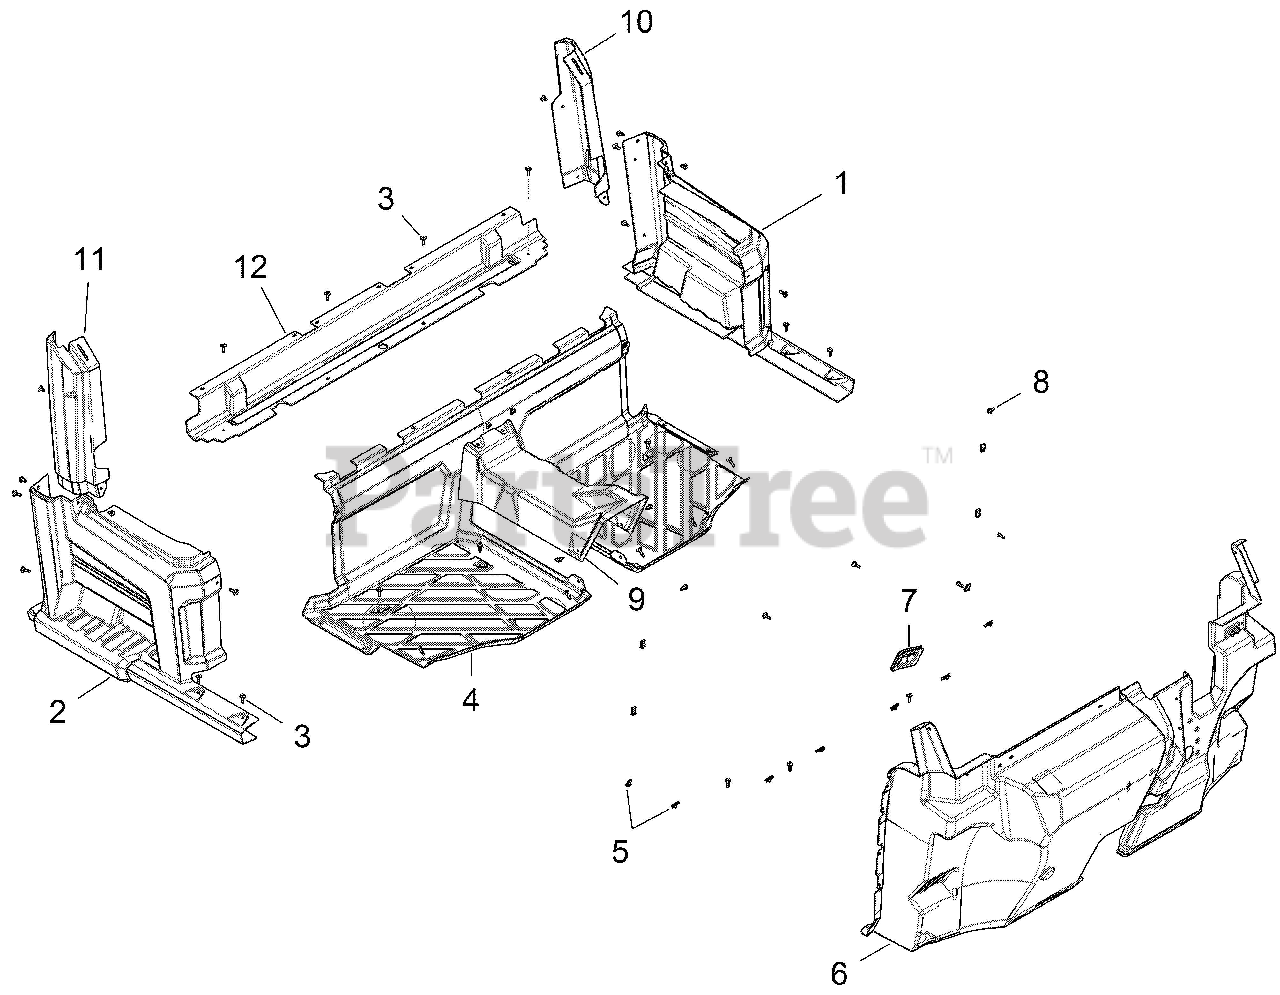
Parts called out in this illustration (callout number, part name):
1	FENDER, FRONT, W/ROCKER, LH
2	FENDER, FRONT, W/ROCKER, RH
3	SCR-TXTH-M6X1.0X25 RIE
4	FLOOR-BLK
5	CLIP-U SPEED NUT
6	FLOOR-FRONT,BLK
7	GROMMET-STEERING,FLOOR
8	RIVET-TUFLOK,.315-.325X.787 (5
9	COVER-DRIVE SHAFT,FLOOR,BLK
10	FENDER-REAR,UPPER,LH,BLK
11	FENDER-REAR,UPPER,RH,BLK
12	PANEL,CLOSEOFF CTR,ROUTER,BLK
